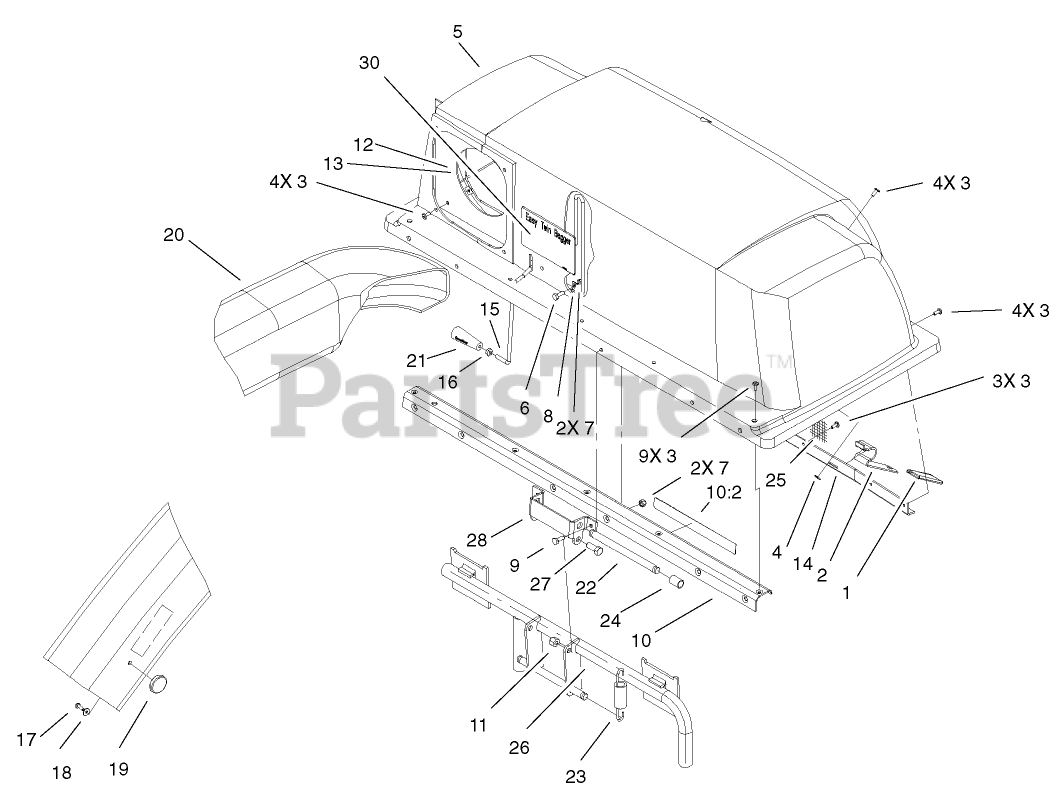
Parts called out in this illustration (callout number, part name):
2	LATCH-BAGGER, TOP
3	RIVET-BLIND
4	WASHER-FLAT
5	TOP-BAGGER
6	SCREW-HH
7	NUT-LOCK, NI
8	CLAMP
9	SCREW-HH
10	BAG STIFFENER ASM
10:2	DECAL-CAUTION
11	NUT-LOCK, NI
12	CLAMP-SEAL
13	SEAL-CHUTE
14	SUPPORT-SCREEN
15	FEELER-FILL, BAG
16	NUT-JAM
17	SCREW-PPHTF
18	WASHER-PLAIN
20	CHUTE-DISCHARGE
21	HANDLE-TAPERED
22	PIN-SPRING
23	SPRING-EXTENSION
24	SPACER
25	SCREEN-BAGGER
26	FRAME ASM
27	SCREW-HH
28	HINGE-BAG, TOP
30	DECAL
